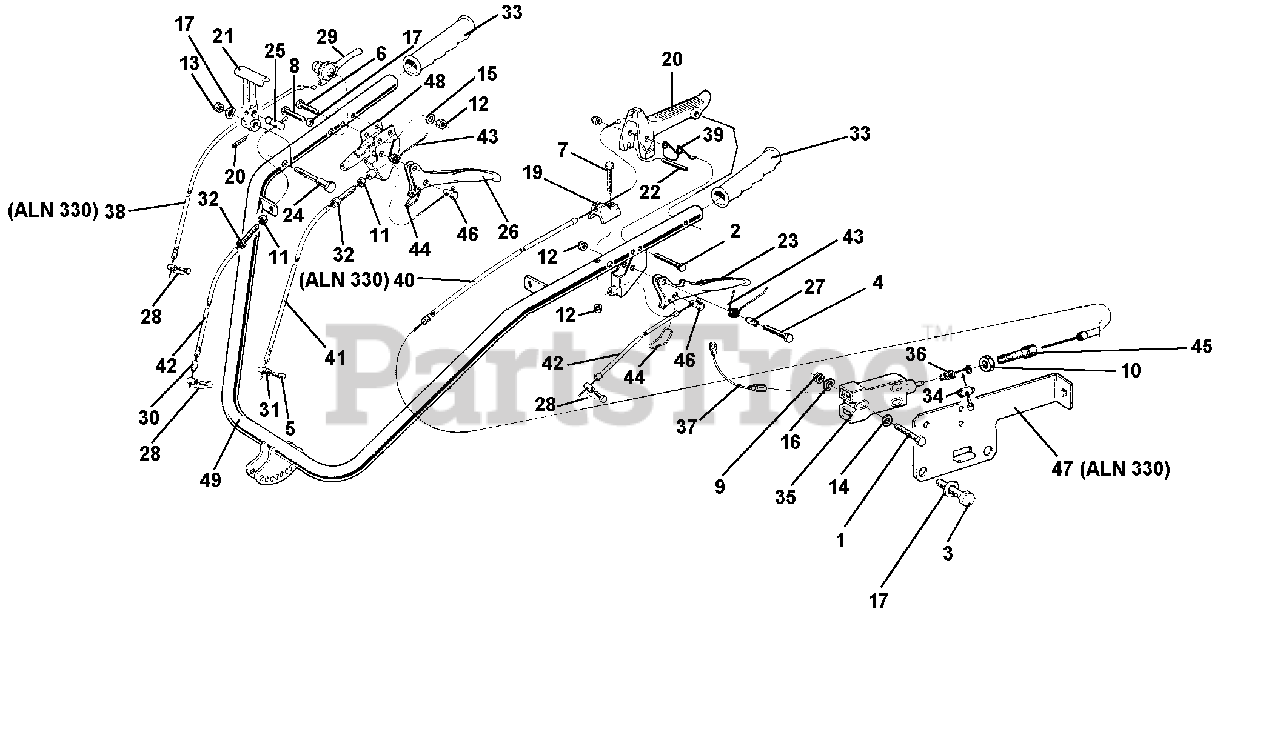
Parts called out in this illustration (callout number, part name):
1	SCREW TE M4 X 25
2	SCREW TE M6 X 45
3	SCREW TE M8 X 12
4	SCREW M6 X 25
5	SCREW TE M6 X 16
6	SCREW M6 X 40
7	SCREW M6 X 35
8	SCREW TE M8 X 40
12	NUT, SELF LOCKING M6
13	NUT, SELF LOCKING M8
14	FLAT WASHER 4.3
15	WASHER, LOCK 6.4
16	LOCK WASHER B 4.3
17	WASHER, LOCK 8.4
18	PIN, LOCKING 4 X 20
19	SHEATH STOP OF MOTOR STOP
20	MOTOR STOP LEVER
21	LEVER DIFFERENTIAL LOCKING
22	LEVER STOP FOR MOTOR STOP
23	CLUTCH LEVER
25	DRILLED PIN
27	LEVER SPACER
28	CLAMP, CABLE
29	LEVER, ACCELERATOR
30	END, SHEATH
31	PIN, CABLE CLAMP
32	SCREW, ADJUSTING M8
34	CABLE CLAMP
35	STOP SWITCH
36	SWITCH SPRING
37	SWITCH CABLES
38	WIRE, SHEATH 1850 GAS
39	MOTOR STOP LEVER SPRING
40	SHEATH CABLE
41	SHEATH CABLE
42	SHEATH CABLE
43	LEVER SPRING
45	ADJUSTING SCREW
47	SUPPORT FOR ACME STOP SWITCH
48	COUPLING FOR DOUBLE LEVER
